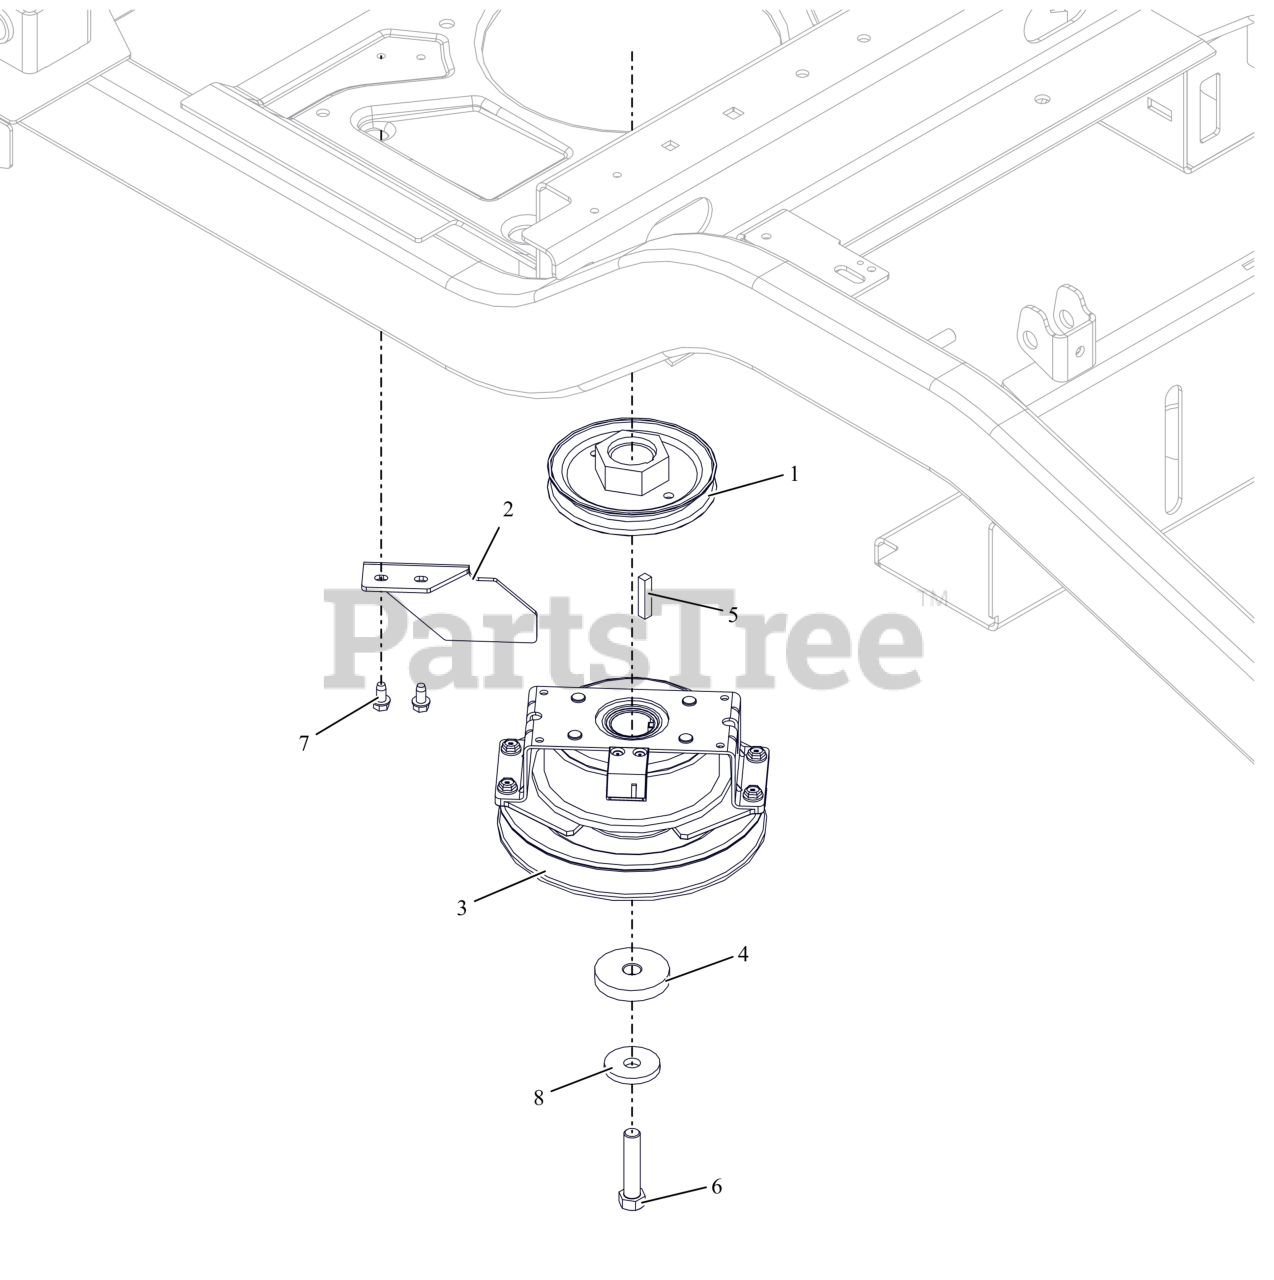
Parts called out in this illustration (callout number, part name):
1	WLDMT,PULLEY-4.50ODX1.127
2	BRKT, CLUTCH STOP HD
3	CLUTCH, OGURA DBLS SPRG 1.13"
4	SPACER, .474/.459X2.00X.350
5	KEY-SQ .25 X 1.25 X .25 SAE
6	BLT, HEX .44-20X2.00 G8 ZCC NT
7	SCR-TAP .25-20X.50 HWH ZCC
8	WASHER, 7/16" SPRING DISK
